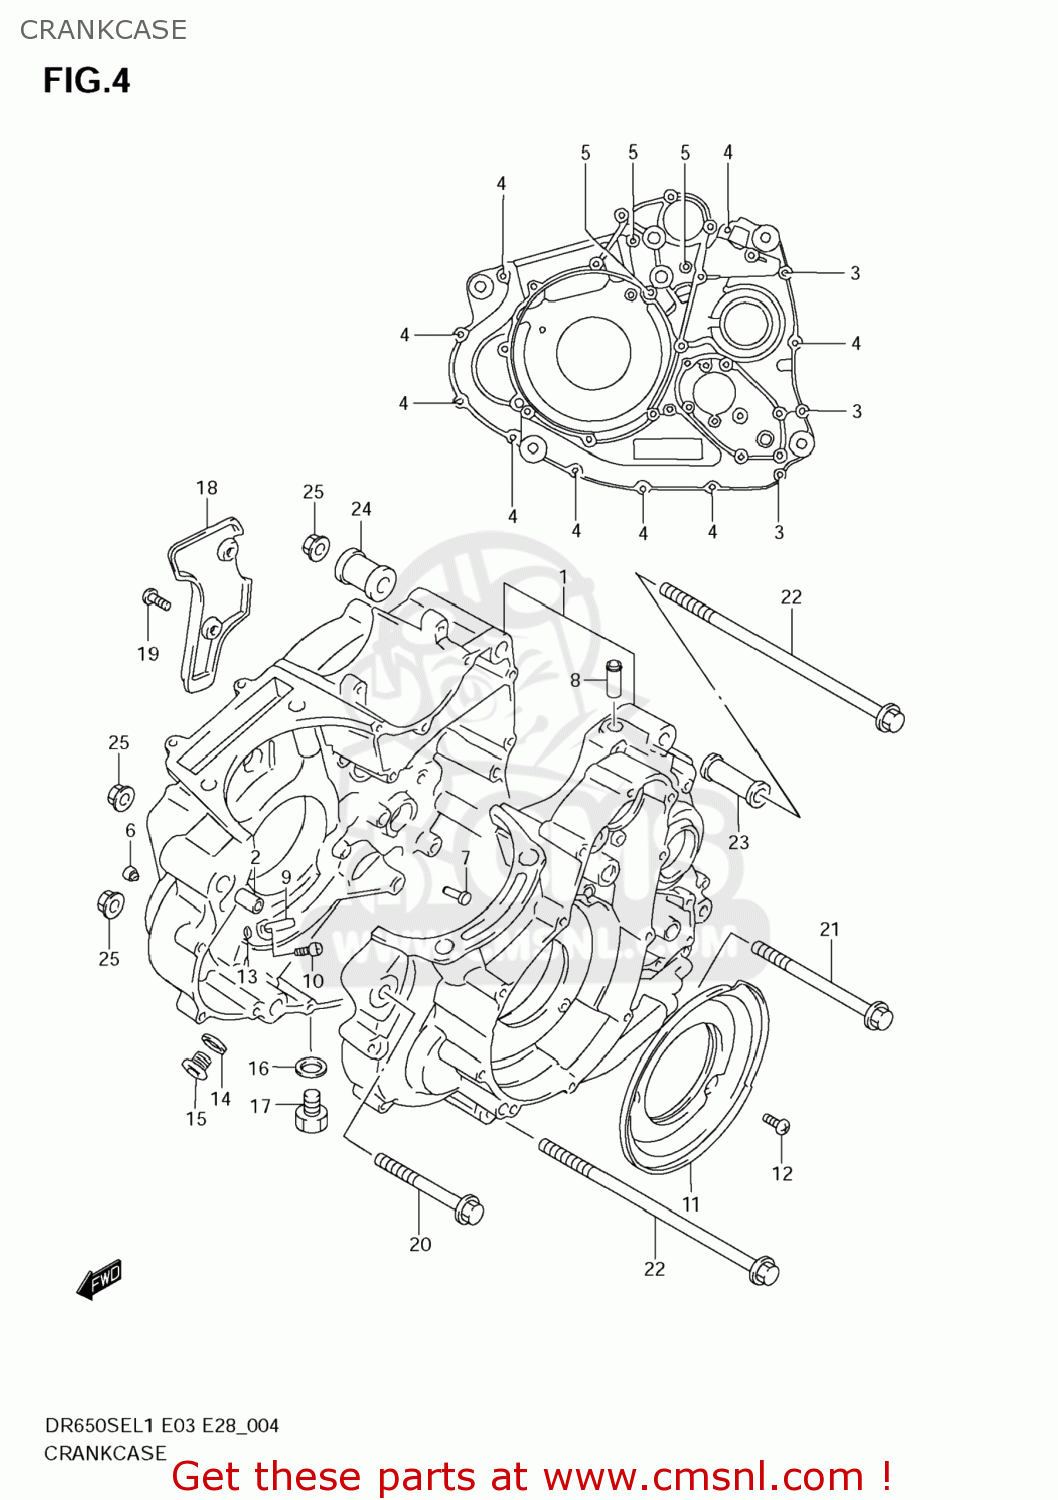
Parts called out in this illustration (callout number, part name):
1	CRANKCASE SET
2	PIN
3	BOLT(6X60)
4	BOLT(6X40)
5	BOLT
6	JET,OIL GALLERY
7	RIVET
8	UNION
9	JET,PISTON COOLING
10	BOLT(6X12)
11	SEPARATOR,CRANKCASE OIL
12	SCREW
13	O RING(D:1.2,ID:4)
14	GASKET(13.8X18.8X4.8) (NAS)
15	PLUG,14X12
16	GASKET(13.8X18.8X4.8) (NAS)
17	PLUG(14X12)
18	COVER,BREATHER
19	SCREW
20	BOLT(10X100)
21	BOLT(10X130)
22	BOLT(10X235)
23	SPACER,ENGINE MOUNT(L:65)
24	SPACER,ENGINE MOUNT(L27)
25	NUT
